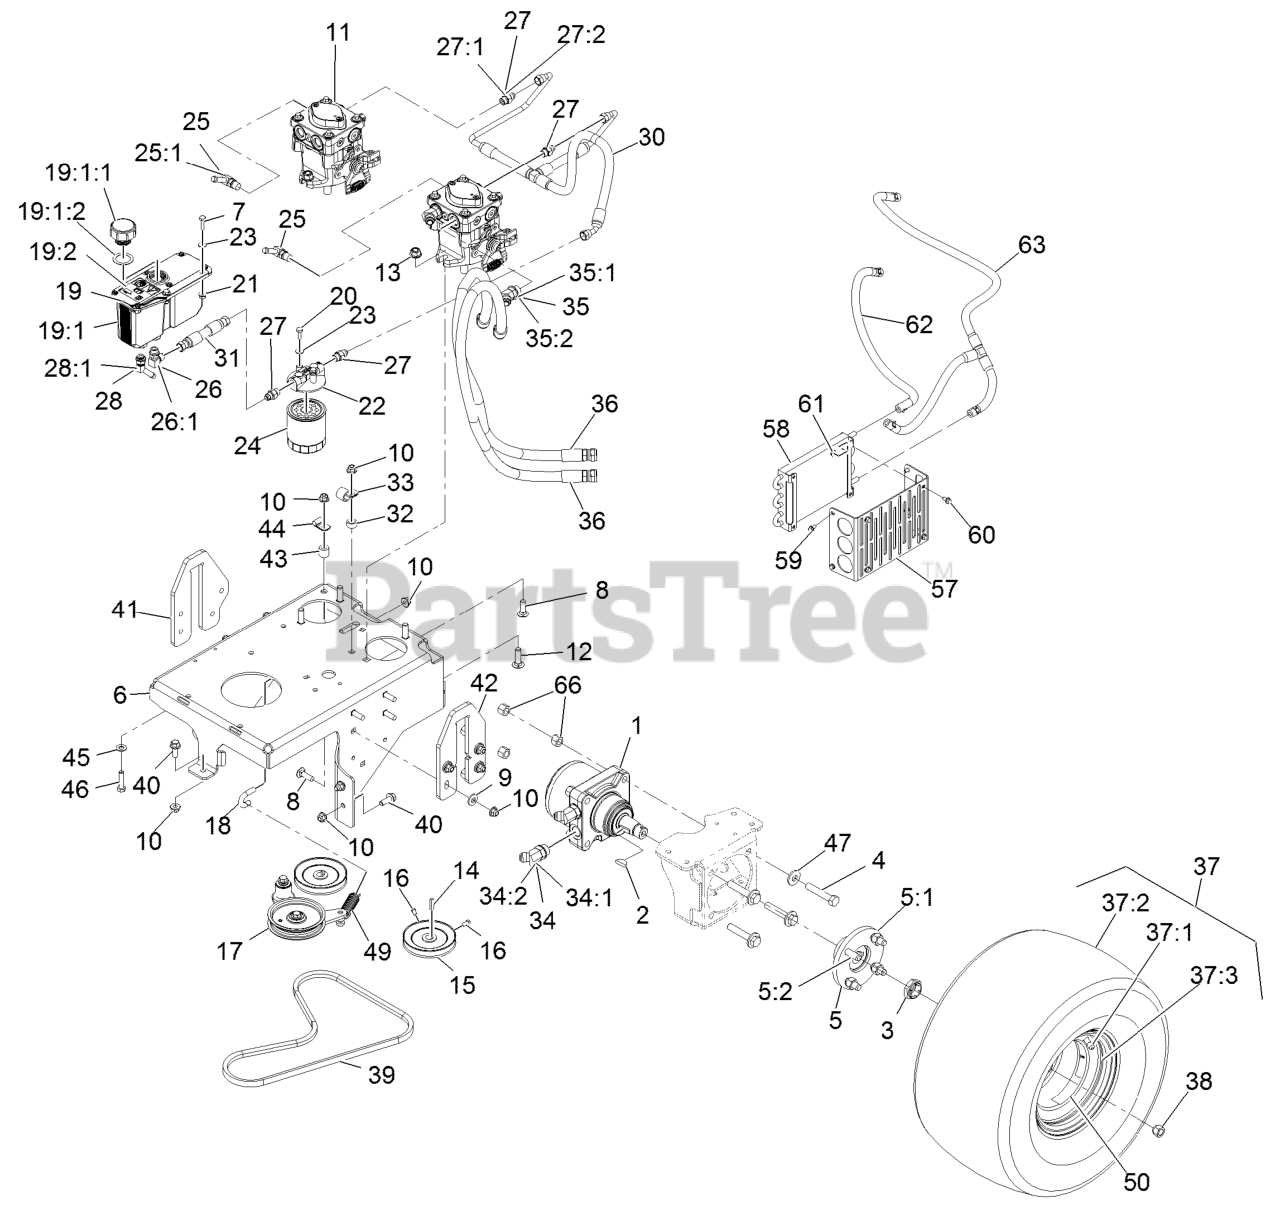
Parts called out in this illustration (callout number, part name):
1	MOTOR-WHEEL
2	KEY-WOODRUFF
3	LOCKNUT
4	SCREW-HH
5	WHEEL HUB / STUD ASM
5:1	HUB-WHEEL
5:2	STUD-TYPE, DRIVE
6	BASE, ENGINE
7	SCREW-HH
8	BOLT-CARR
9	WASHER-BELLEVILLE
10	NUT-HF, NI
11	PUMP - HYDRAULIC
12	BOLT-CARR
13	NUT-HF, NI
15	PULLEY-PUMP
16	SCREW-SET
17	PUMP IDLER ASM
18	ANCHOR, SPRING
19	RESERVOIR ASM
19:1	Cap-Reservoir, HYD
19:1:1	GASKET-CAP
19:1:2	DECAL-WARNING
19:2	SCREW-HH
20	NUT-HHF
21	HEAD-FILTER
22	WASHER-FLAT
23	FILTER-25 MICRON, BI-DIRE
24	FITTING-ELBOW, 90
25	O-RING
25:1	FITTING-ELBOW, 90 DEG
26	O-RING
26:1	FITTING-STRAIGHT
27:2	FITTING-BARBED, 45 DEG
28	FITTING-BARBED, 45 DEG
28:1	O-RING
30	HOSE ASSEMBLY - CHARGE
31	HYD HOSE ASM
32	SPACER-WHEEL
33	CLIP-LOOM
34	FITTING-HYD, 45 DEG
35	FITTING-HYD, 45 DEG
36	HYD HOSE ASM
37	WHEEL/TIRE ASM
37:1	RIM-8 INCH
37:3	Stem-Valve
38	NUT-LUG
39	BELT-V, LOWER PTO
40	SCREW-HHF 3/8-16 X 1
41	PLATE-LIFT, RH
42	PLATE, LIFT LH
44	CLIP-TUBE
45	WASHER-FLAT
46	SCREW-HH
47	WASHER-SPRING
49	SPRING-IDLER
50	DECAL-TORQUE, WHEEL HUB LUG
57	BRACKET, COOLER MOUNTING
59	SCREW-HWH
60	SCREW-HHF
61	NUT-KEPS
62	HOSE-HYDRAULIC
63	HOSE ASM-HYD LP 3/8
66	NUT-LOCK, NI
67	TIE-CABLE
